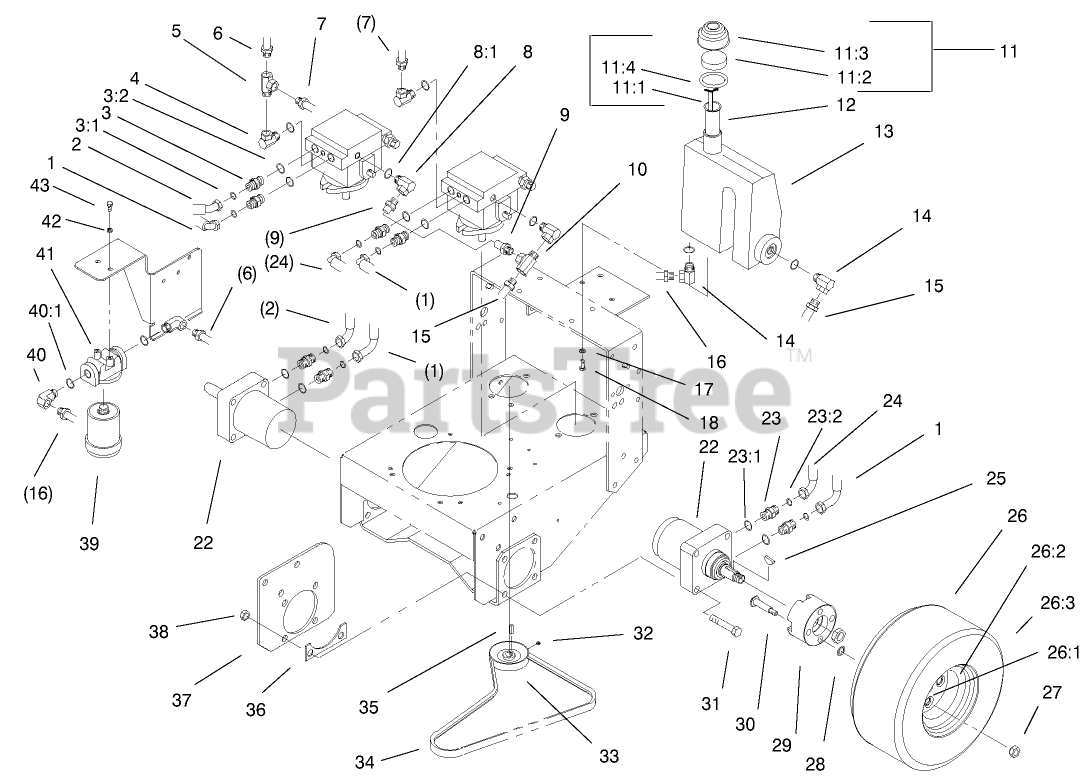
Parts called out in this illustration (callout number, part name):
1	HYDRAULIC HOSE ASM
2	HYDRAULIC HOSE ASM
3	FITTING-STRAIGHT
3:1	O-RING
3:2	O-RING
4	SWIVEL-PIPE, FEMALE
5	FITTING-HYD, TEE
6	HYD HOSE ASM
7	HYD HOSE ASM
8	FITTING-HYD, 90 DEG
8:1	O-RING
9	HYD HOSE ASM
10	FITTING-HYD, TEE
11	OIL CAP ASM
11:1	DIPSTICK
11:2	FOAM-FILTER, OIL CAP
11:3	CAP-OIL
11:4	O-RING
12	SCREEN-FILLER
13	RESERVOIR-OIL
14	FITTING-HYD, 90 DEG
15	HYDRAULIC HOSE ASM
16	HYD HOSE ASM
17	WASHER-LOCK
18	SCREW-HH
22	WHEEL MOTOR ASM
23	FITTING-STRAIGHT
23:1	O-RING
23:2	O-RING
24	HYDRAULIC HOSE ASM
25	KEY-WOODRUFF
26	ASM-Wheel & Tire
26:1	STEM-VALVE
26:2	WHEEL
27	NUT-LUG
28	PUSHNUT
29	HUB-WHEEL
30	SCREW-HH
31	SCREW-HH
32	SCREW-SET
33	PULLEY-PUMP
34	BELT-V
35	KEY-PUMP
36	SPACER-FRAME
37	PLATE-FRAME
38	NUT-LOCK, NI
39	CARTRIDGE-FILTER, OIL
40	FITTING-HYD, 90 DEG
40:1	O-RING
41	HEAD-FILTER
42	WASHER-LOCK
43	SCREW-HH
